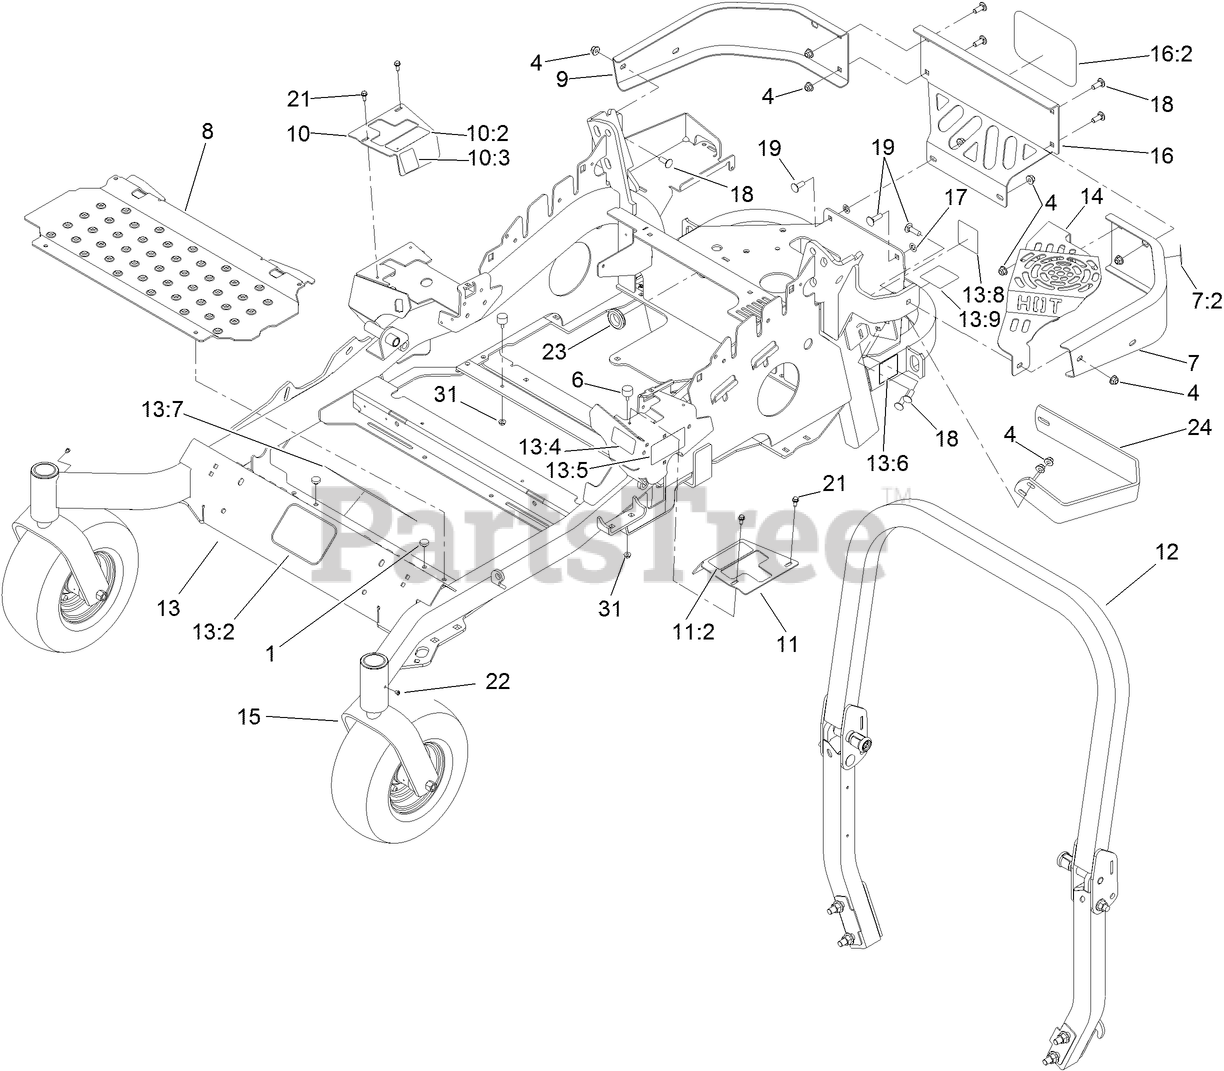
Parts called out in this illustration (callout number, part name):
1	BUMPER
4	NUT-HF, NI
6	BUMPER-RUBBER (W/ STUD)
7	BUMPER-REAR, LH
7:2	DECAL-CAUTION
8	FLOORPAN
9	BUMPER-REAR, RH
10	COVER ASM-MOTION CONTROL
10:2	DECAL-MOTION CONTROL
10:3	DECAL-PARK BRAKE
11	COVER ASM-MOTION CONTROL
11:2	DECAL-MOTION CONTROL
12	ROPS ASM
13	FRAME ASM
13:2	DECAL
13:4	DECAL-FUEL FILL
13:6	DECAL-BELT DRIVE
13:7	DECAL-SLOPE
13:8	DECAL-SPARK ARRESTER
13:9	DECAL-BYPASS
14	GUARD-MUFFLER
15	FRONT CASTER W/FORK ASM
16	REAR GUARD ASM
16:2	DECAL
17	NUT-PUSH
18	SCREW-CARR
19	BOLT-CARR
21	SCREW-HWH
23	GROMMET
24	GUARD-MUFFLER, SIDE
31	NUT-HF
